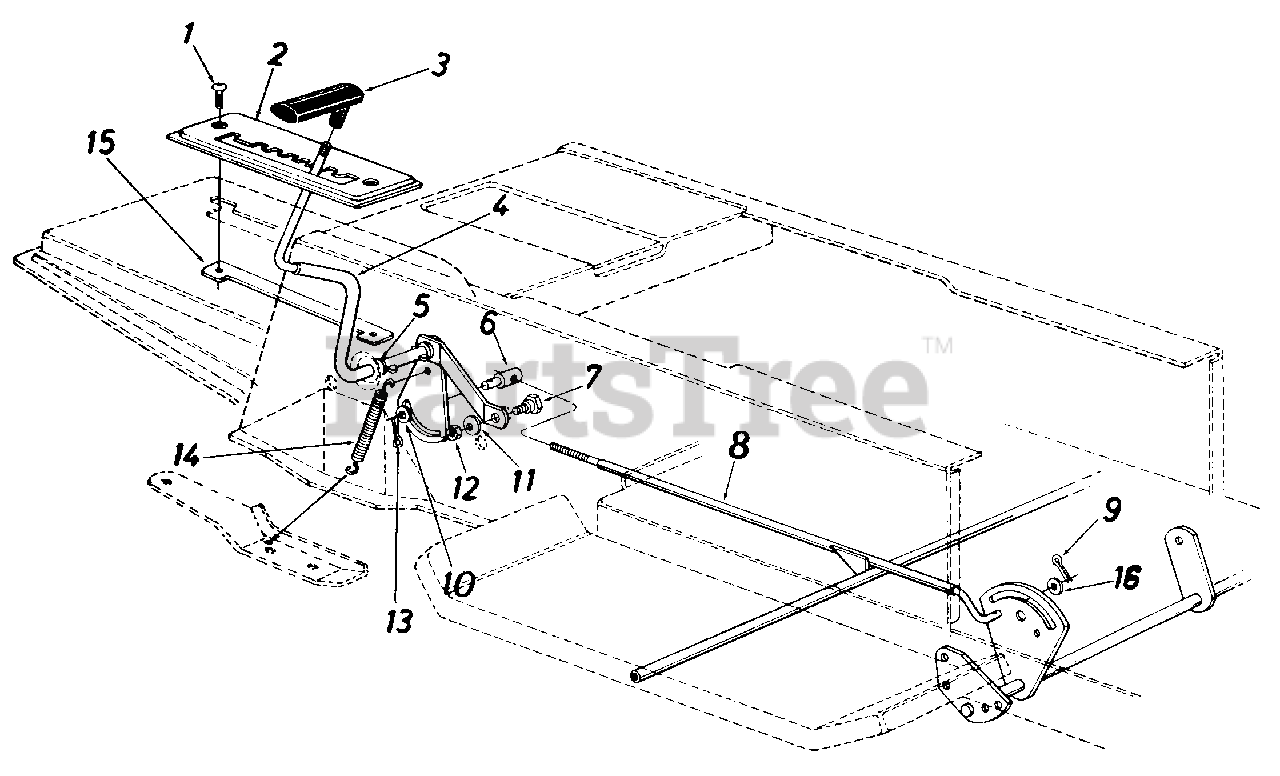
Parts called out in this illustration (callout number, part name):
1	Truss Mach. Scr. 1/4-20 x .75" Lg.
4	Speed Selector Cam Ass'y.
5	Flat Washer .53" I.D. x .93" O.D.
6	Ferrule 3/8-24 x .37" Dia.
7	Shoulder Bolt .435" Dia. x .160
8	Speed Control Rod Ass'y.
9	Cotter Pin 3/32" Dia. x .75" Lg.
10	Fl-Wash. .39" I.D.
11	L-Wash. 5/16" I.D.*
12	Hex Nut 5/16-18 Thd.
13	Hairpin Cotter 1/8" Dia.
14	Spring
15	Clamping Plate
16	Fl-Wash. .47" I.D> x .88" O.D.
